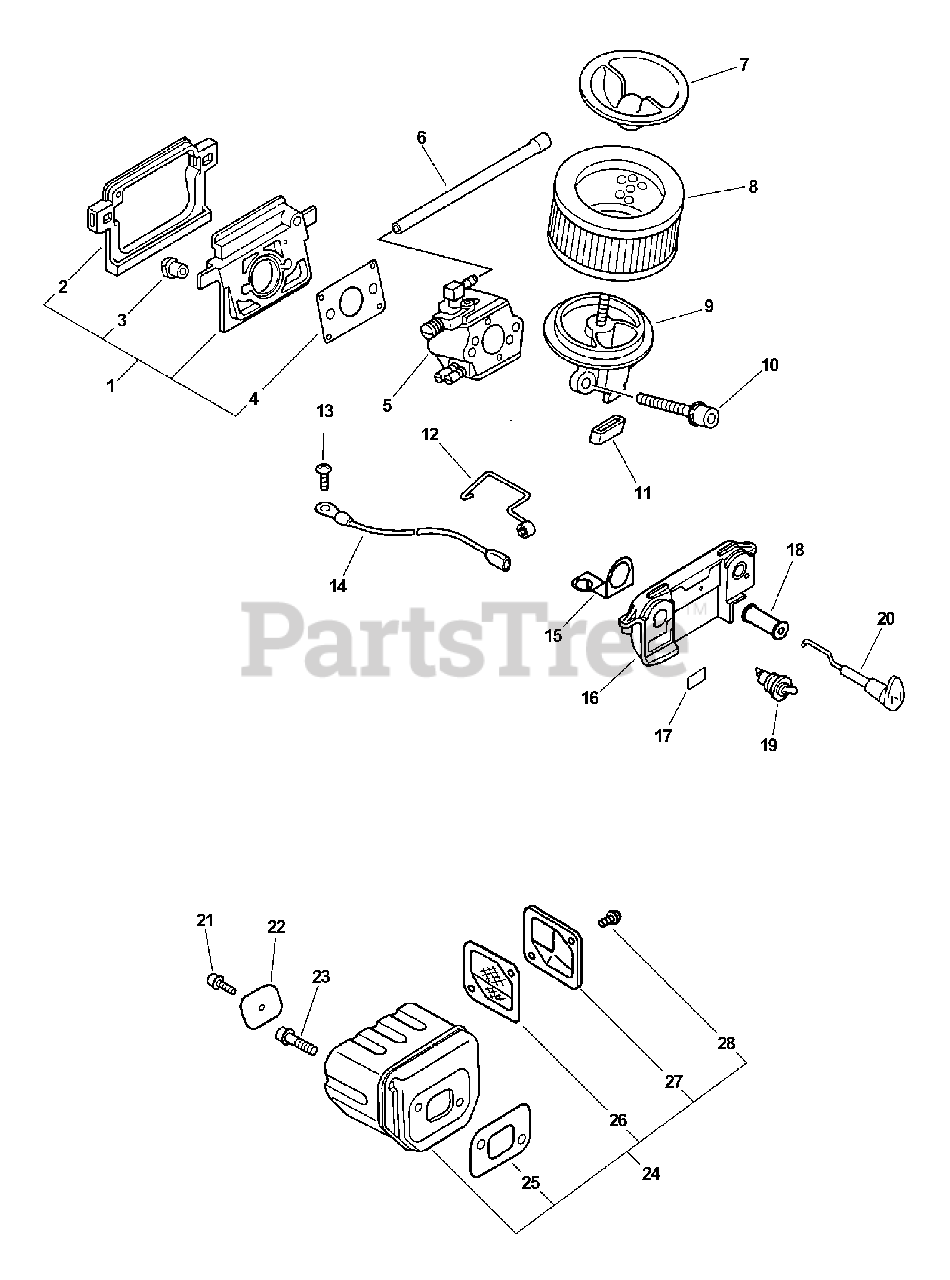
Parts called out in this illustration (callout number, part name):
1	INSULATOR KIT
2	CUSHION
4	GASKET, INTAKE
5	CARBURETOR
6	PIPE, IMPULSE 3×5×110
7	COVER, AIR FILTER
8	FILTER, AIR
9	ADAPTER, INTAKE
10	BOLT 5×50
12	ROD, THROTTLE
13	SCREW 4×6
14	LEAD - GROUND
15	TERMINAL, SWITCH
16	BRACKET, SWITCH
17	LABEL, STOP
18	GROMMET
19	SWITCH, ON-OFF
20	ROD, CHOKE
21	BOLT 4×6
23	BOLT 5×14
24	MUFFLER ASSY
25	GASKET, MUFFLER
26	SCREEN, SPARK ARRESTER
27	COVER, MUFFLER
28	SCREW TAPPING 4×8
